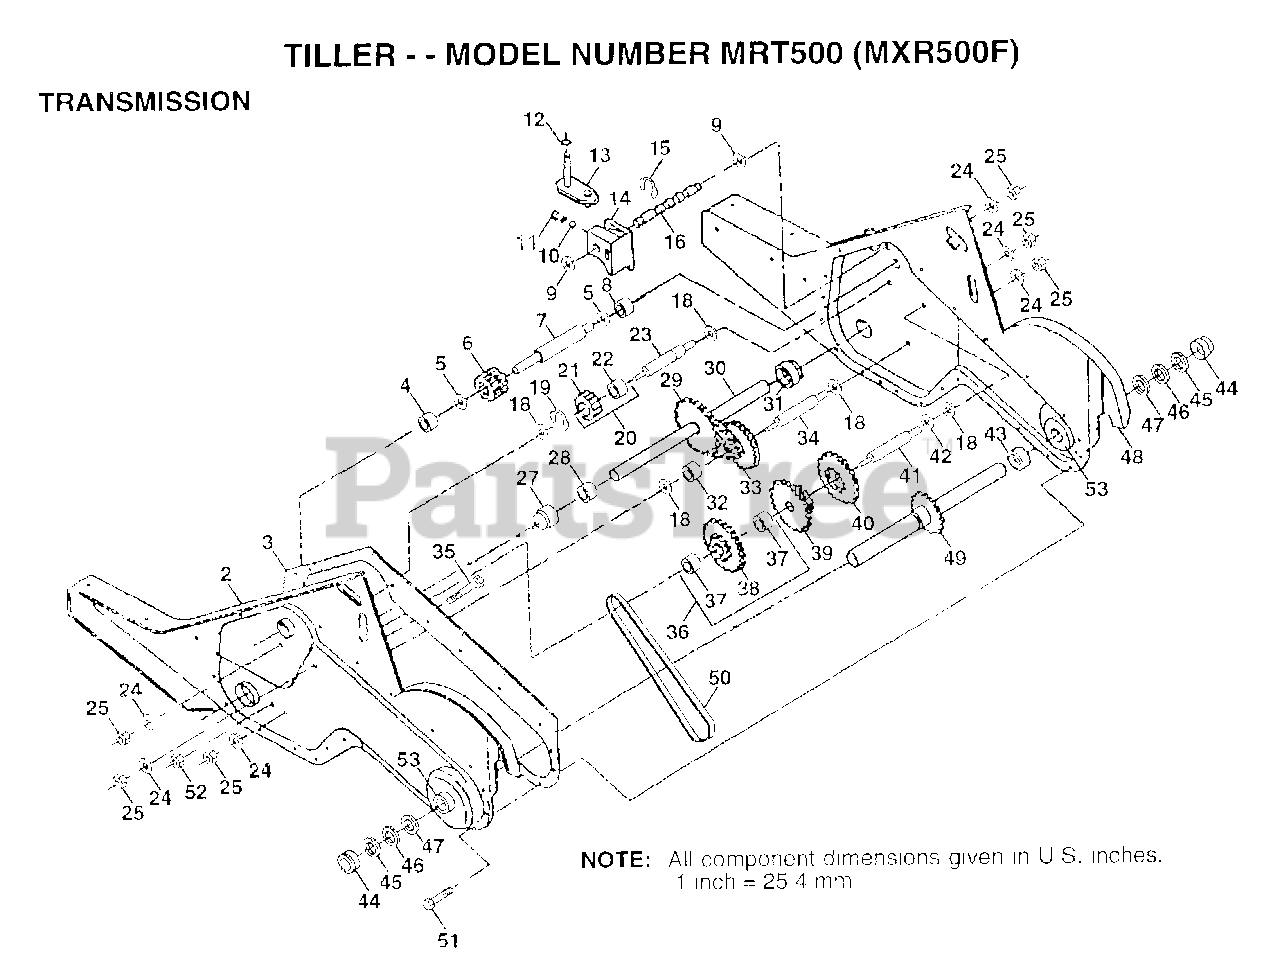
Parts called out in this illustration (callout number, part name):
2	GEARCASE LH W/BRG
3	GASKET TI
4	NEEDLE BRNG LT
5	"T, BEARING"
6	GEAR PINION INPUT
7	"SHAFT.INPUT.""D"""
8	"TI, BEARING"
9	WASHER SEAL CRT
11	SPRING-SHIFT CRT
12	O-RING TI
13	BRACKET ASM SHIFT
14	SHIFT FORK TI
15	KLIP RING
16	SHAFT.SHIFT.4.250
18	WASHER
19	KLIP RING
20	GEAR ASSY CRT
21	GEAR-REV IDLR CRT
22	NEEDLE BEARING TI
23	SHAFT CRT
24	LOCKWASHER
25	NUT.ASF.HEX.7/16
27	BEARING.SHAFT.LH.
28	BUSHING TI
29	CHAIN CRT
30	GROUND SHAFT ASSY
31	BEARING.SHAFT.RH.
32	SPACER TI
33	SPRCKT 8 GEAR CRT
34	SHFT 2ND RED. CRT
35	SCRW WHIZ LOK CRT
36	SPROCKET ASM.
37	BEARING
39	GEAR TI
40	GEAR TI
41	REDUCTION SHFT TI
42	BRNG RACE
43	SPACER TI
44	CUP.FORMED.
45	RING SPIRAL CRT
46	SEAL RING RUBBER
47	OIL SEAL STD
48	GEARCASE RH W/BRG
49	TINE SHAFT
50	CHAIN.50 LINK TI
51	SCREW CRT
52	NUT.HEX.5/16-18
